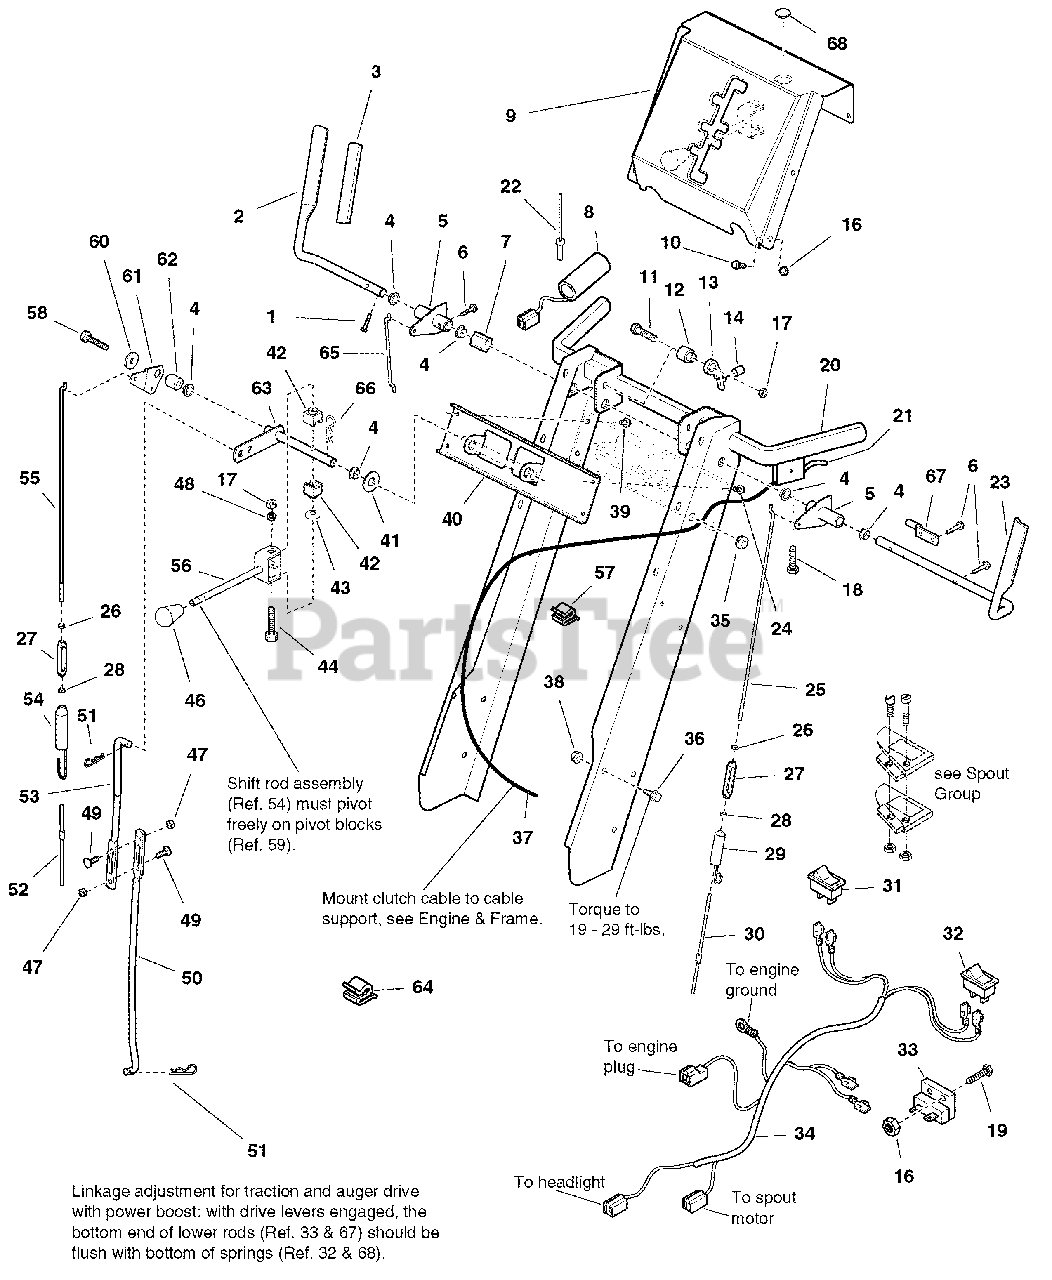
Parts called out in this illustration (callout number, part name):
1	CAPSCREW, Hex Washer Head, #10-24 x 1
2	HANDLE, Clutch, RH
4	BUSHING, Nylon
5	LEVER & TUBE ASSEMBLY, Clutch
6	CAPSCREW, Hex Washer Head, #12-24 x 1
7	GUIDE, Control
8	GRIP, Heated
10	CAPSCREW, Hex Head, 1/4-20 x 3/4
11	SCREW, Hex Whiz Lock 5/16-18 x 1 1/2
12	SPACER
13	LATCH, Control
14	SPRING, Compression
16	NUT, Hex Flange 1/4-20 Yellow
17	NUT, Hex Flange 5/16-18 ESNA Black
18	SCREW-PAN HD TORX #10 x 1/2
19	CAPSCREW-HEX HD 1/4-20 x 3/4
20	HANDLE ASSEMBLY
21	TRIGGER ASSEMBLY, Easy Turn Clutch Cable
23	HANDLE, Clutch
24	CAPSCREW, Hex Washer Head Taptite 1/4-20 x 3/4
26	NUT, LH, Machine Screw, Hex, #10-24
28	NUT, RH, Machine Screw, Hex, #10-24
30	ROD, Clutch
31	SWITCH, Rocker, Spout Rotator
32	SWITCH, Hand Warmer, Off, Warm, Hot
33	RESISTOR BLOCK
34	HARNESS Assembly
36	CAPSCREW, Hex Whiz Lock, 5/16-18 x 3/4
37	CABLE & HANDLE ASSEMBLY, Clutch (Includes Ref. 21)
38	NUT, Hex Flange, 5/16-18
39	CAPSCREW, Hex Washer Head Taptite, 1/4-20 x 3/4
40	BRACKET, Shift Control
41	WASHER, 1/2
42	BLOCK, Pivot
43	WASHER, Curved, 1/2
44	CAPSCREW, Hex Head, 1/4-20 x 2 1/4
47	NUT, KEPS 1/4-20
48	LOCKWASHER, Spring, 1/4
49	CARRIAGE BOLT, 1/4-20 x 3/4
50	ROD, Shift, Lower
51	PIN, Quick .250 x .38
52	ROD, Clutch, Lower
53	ROD, Shift, Upper
55	ROD, Clutch, Upper
56	SHIFT ASSEMBLY, Rod & Clevis
57	CLIP, Wire
58	SCREW, Hex Whizlock Flange 5/16-18 x 1 1/2
60	WASHER, 5/16 x 1 x .13
61	LEVER, Clutch
63	ROD & ARM ASSEMBLY, Pivot
65	ROD, Clutch
66	PIN, Cotter
67	ROD, Control
